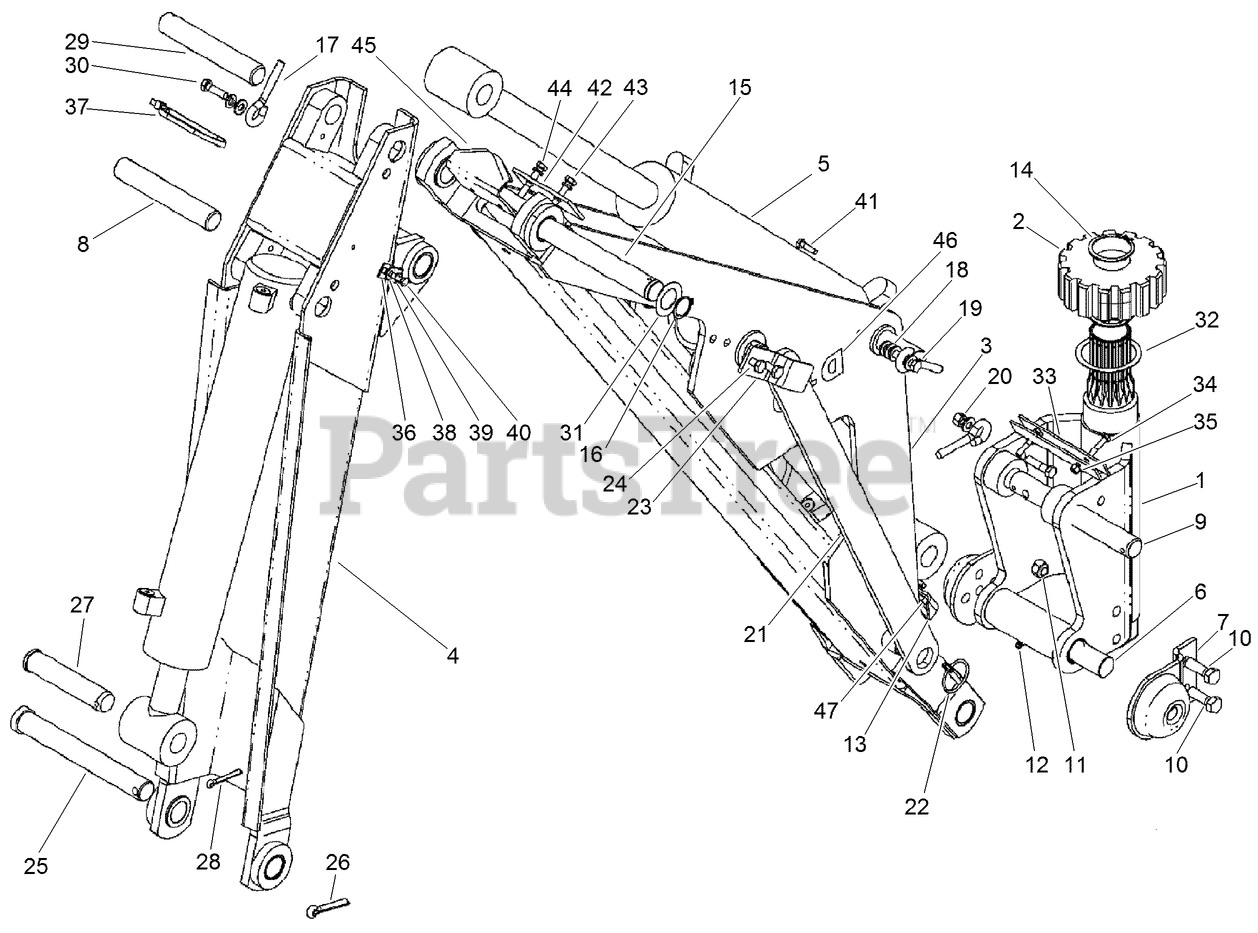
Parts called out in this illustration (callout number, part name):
1	WELDMENT-Backhoe King Post
2	GEAR-Driven
3	WELDMENT-Backhoe Boom
4	WELDMENT-Dipper Stick
5	CYLINDER-Backhoe
6	PIN-Boom Pivot
7	BUMPER-Rubber, Swing
8	PIN-Backhoe
9	PIN-King Post Pivot
10	SCREW-HH
11	NUT-LOCK, HEX
12	FITTING-Lube 1/4-28 Tpr SAE-LT .54 Long
13	BRACKET-Hose Retainer
14	RING-Retainer
15	PIN-Dipper Pivot
16	RING-Retaining Ext Basic #112 Pltd
17	PIN-RETAINER
18	WASHER-FLAT
19	BOLT-hex, 3/8 NC x 1-1/2 inch
20	NUT-HEX
21	LINK-Transport
22	PIN-KLIK
23	BRACKET-Pin Retainer
24	SCREW-HH
25	PIN-Bucket Hinge
26	PIN-Cotter 0.375 x 2.00 in ZN
28	PIN-COTTER
29	BOLT
30	WASHER-Spring Lock, Reg 3/8 ZND
31	WASHER-Flat 1-9/16 CAD
32	SHIM-Kingpost
33	BRACKET-Hose Mtg
34	BOLT-Hex Hd 0.250 x 1.50 GR8 ZND
35	NUT-Prev Trq 1/4 GRA CAD NONDIR
36	CLAMP-Tube
37	STRAP-TIE
38	WASHER-FLAT
39	WASHER-Spring Lock Reg 0.250 in ZND
41	BOLT-Hex Hd 0.250 x 1.00 GR8 ZND
42	CUSHION-Anti-Wear
43	WASHER-Lock, 5/16 inch
44	BOLT-Hex Hd 0.312 x 2.00 GR8 ZND
45	CLAMP-Tube
46	DECAL-D100 BACKHOE-Model Number
47	CLAMP-Tube
